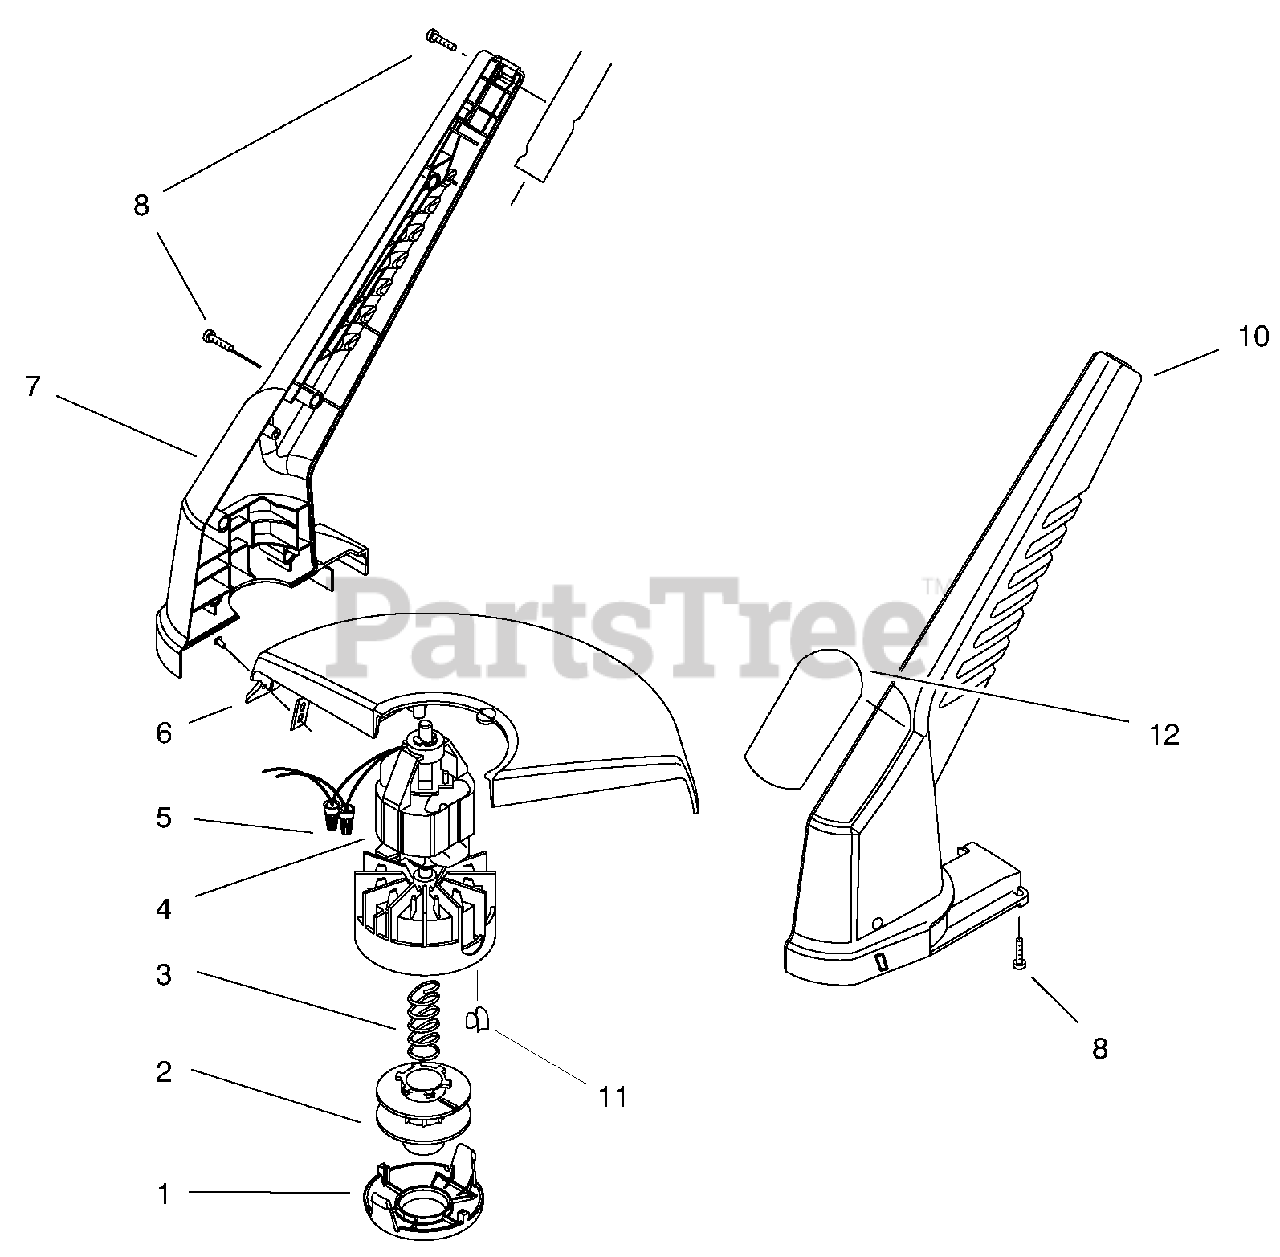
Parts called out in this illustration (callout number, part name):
2	SPOOL - LARGE
3	SPRING - COMPRESSION
4	Motor Assembly (Includes Ref. #11)
5	CONNECTOR-WIRE NUT
6	SHIELD ASM
7	HOUSING-RH
8	SCREW-PPH
10	HOUSING-LH
12	DECAL, 12" TRIMMER/EDGER
